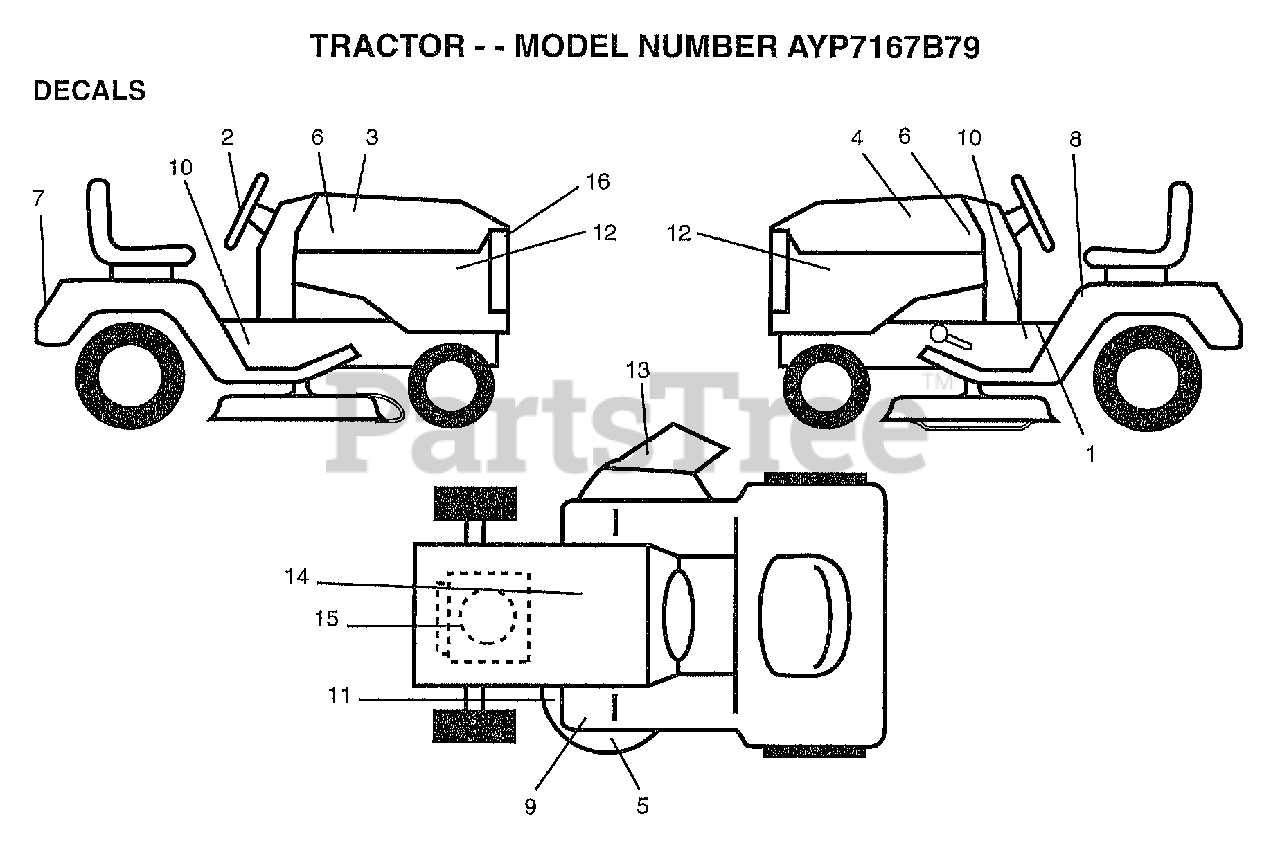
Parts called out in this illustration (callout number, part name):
1	"DECAL DASH,OPER."
2	DECAL STEER WHL
3	DECAL HOOD RH
4	DECAL HOOD LH
5	DECAL DECK WIZ +
6	NAMEPLATE.HD.WIZA
8	"DECAL DANGER,FEND"
10	DECAL CHASSIS WIZ
11	DECAL
12	"DECAL PANEL,SIDE"
13	DECAL DECK MULCH
14	DECAL.BATRY.3-3908
15	DECAL, ENGINE B&S
16	DECAL.LENS.WIZARD
